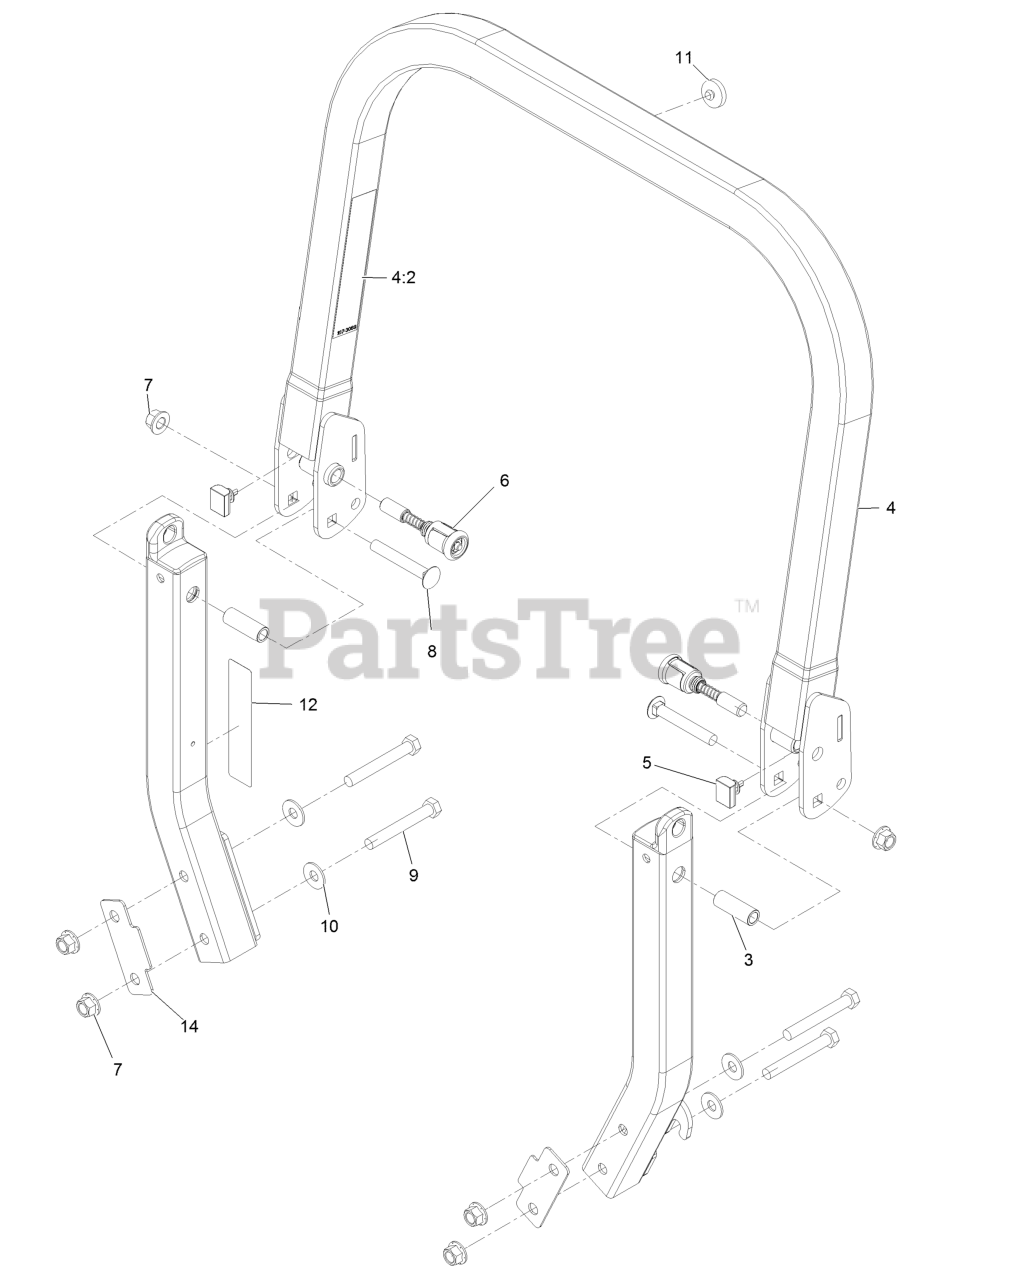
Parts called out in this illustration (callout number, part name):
4	Upper ROPS ASM
4:2	Decal-Warning
5	Bumper-ROPS
6	Pin-Spring
7	Nut-Lock 1/2-13
8	Bolt-Carriage 1/2-13 X 3 1/2
9	Screw-HH
10	Washer, Spring Disc 1/2
11	Bumper-Push-In, Rubber
12	Decal-Caution, Fuel Vent
